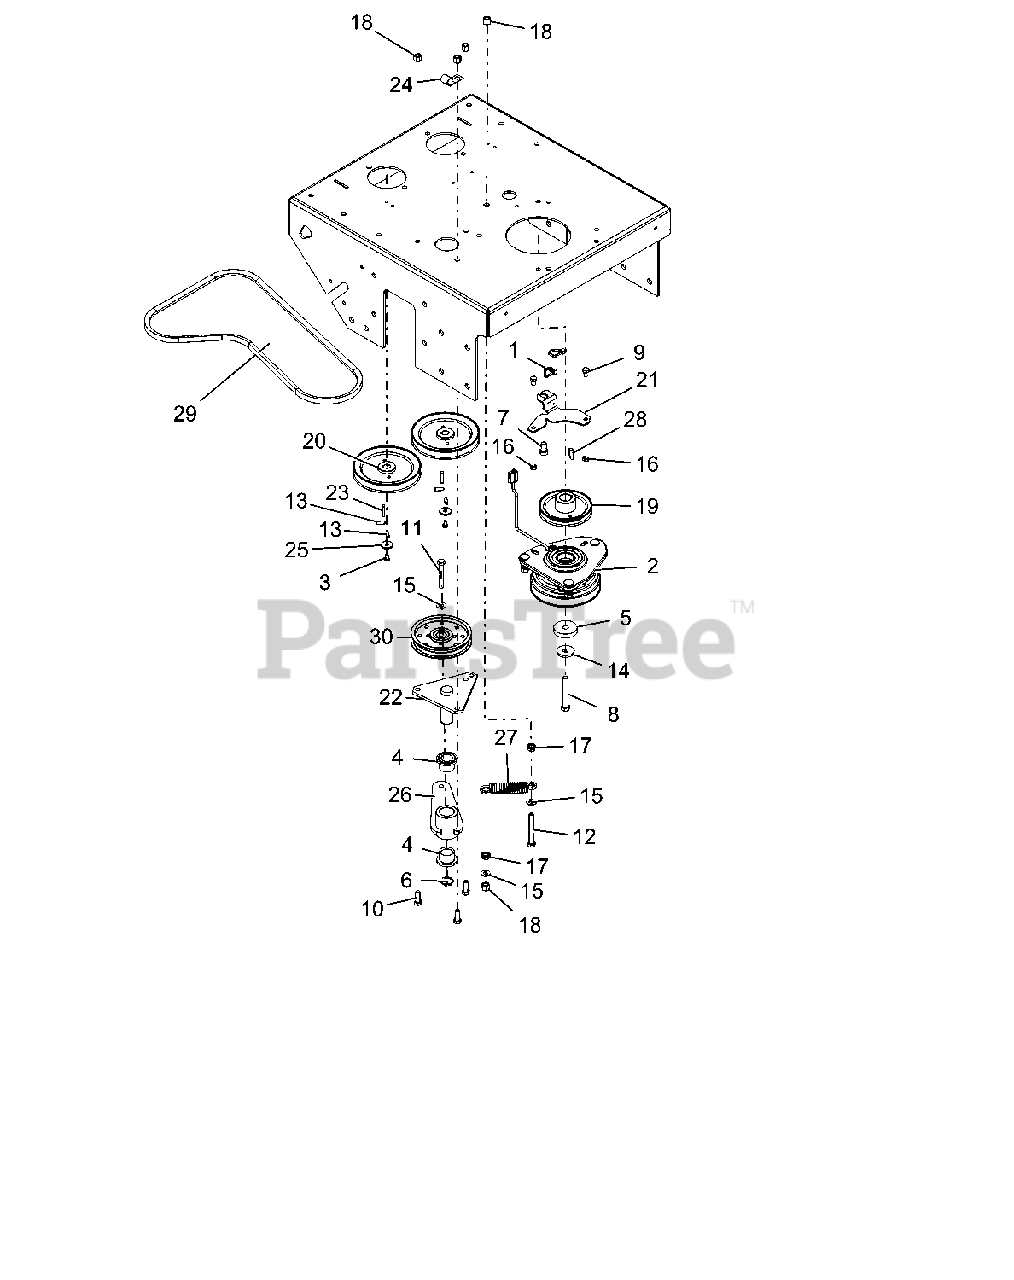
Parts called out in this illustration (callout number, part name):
1	CABLE TIE, .15 X 8.50
2	CLUTCH ASSY, OGURA
3	BOLT, M6X1.00X10 HEX 8.8 Y
4	BRG, FLANGE 1.00 X 1.25 X 1.00
5	SPCR, .450 X 2.00 X .396
6	SNAP, RING, 1.00 X .042 EXT
7	BLT-HEX .44-14X.75 GR5 YWZC
8	BLT-HEX .44-20X3.00 GR8 YWZC NYTORQ
9	BLT-HEX .31-18X.50 GR5 YWZC
10	BLT-HEX .38-16X1.00 GR5 YWZC
11	BLT-HEX .38-16X2.50 GR5 YWZC
12	BLT-HEX .38-16X3.00 GR8 YWZC
13	SCR-SET, 25-20X.75 SKHCUPDL REV
14	WSHR, 7/16" SPRING DISC
15	WSHR-FL-STL.406X.812X.065 YWZ
16	NUT-LK-CTR-JAM .31-18 YWZC
17	@NUT-SPNLK-FLG .375-16 YWZC
18	NUT-LK-NYL .38-16 YWZC
19	PULLEY, V-BELT WLK TRANS DRIVE
20	PULLEY, V-BELT PUMP HYD WLK
21	PLATE, CLUTCH DOG
22	WLDMT, IDLER PIVOT MOUNT
23	KEY, RND - M5XM5XM30
24	P-CLIP, .500 INSULATED
25	WASHER, .250 WIDE HEAVY FLAT Y
26	WLDMT, IDLER ARM
27	SPRG, EXTENSION
28	KEY, .250 X .250 X .995 TPR
29	BELT, HA 55.1 EL AMD OHR
30	PULLEY, FLAT 4.50 X .375 W/BRG
